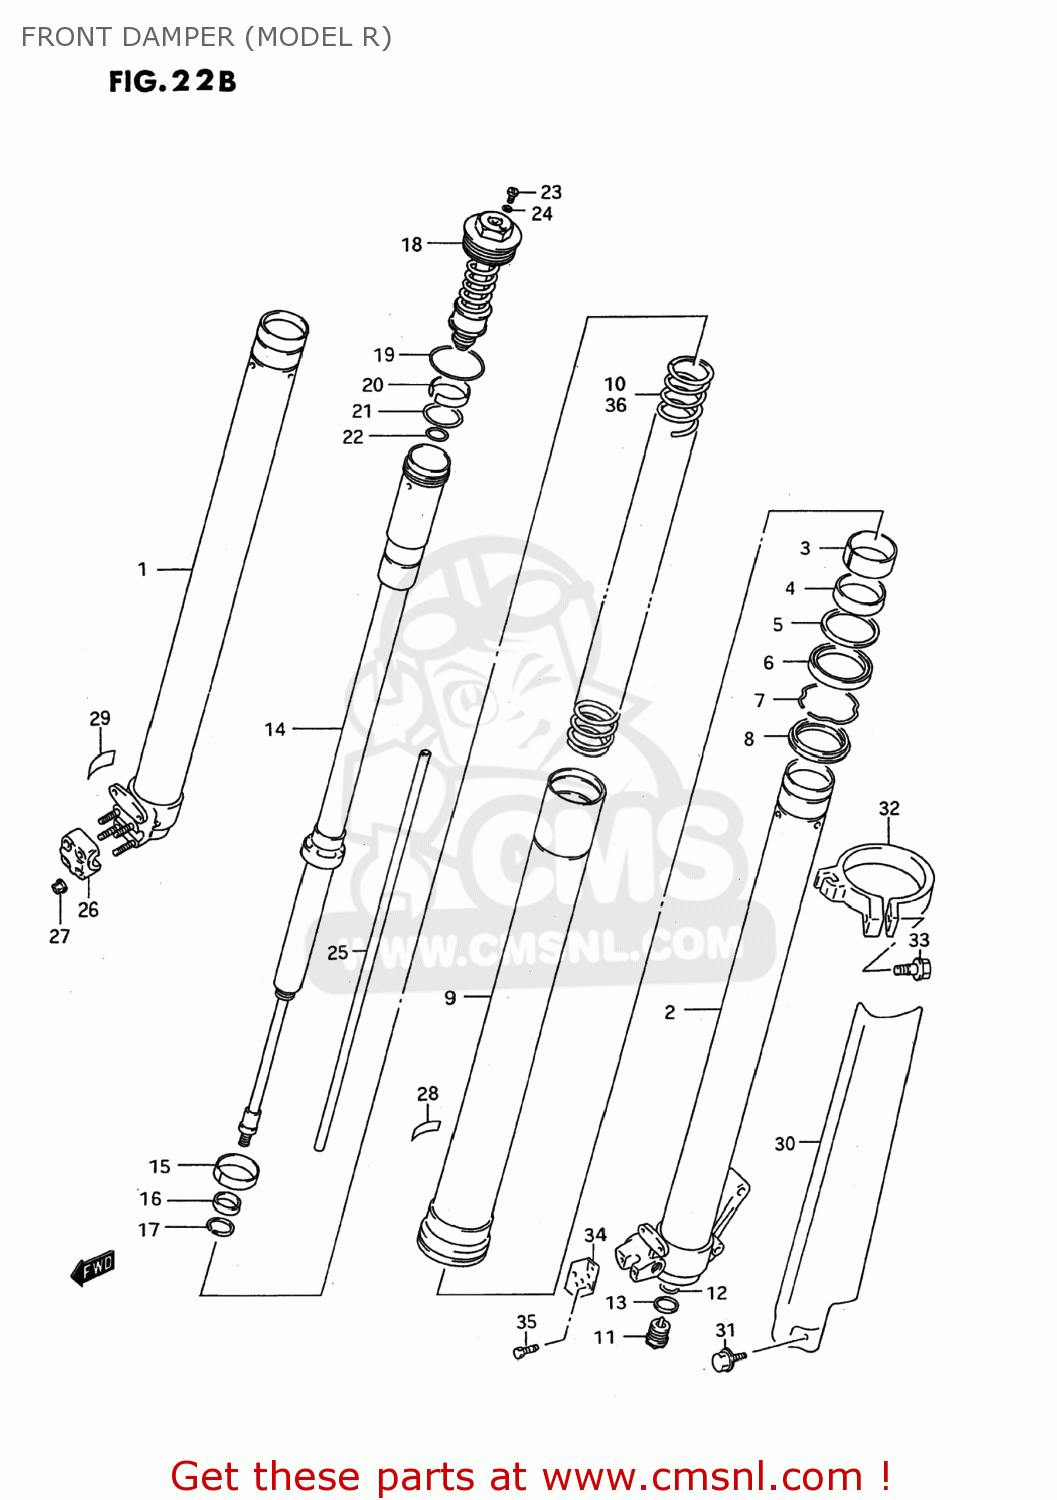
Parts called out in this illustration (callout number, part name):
1	TUBE,INNER,RIGHT
2	TUBE,INNER,LEFT
3	BUSH,SLIDE
4	BUSH,GUIDE
5	SPACER,SEAL
6	SEAL,OIL
7	RING,OIL SEAL STOPPER
8	SEAL,DUST
9	TUBE,OUTER
10	SPRING,MAIN
11	BOLT,CTR
12	GASKET (NAS)
13	O RING,CTR BOLT
14	DAMPER,CARTRIDGE
15	BUSH,DAMPER SLIDE
16	VALVE,OIL LOCK
17	RING,VALVE STOPPER
18	BOLT,FORK
19	O RING
20	BUSH,FORK BOLT SLIDE
21	O-RING,FORK BOLT,CENTER
22	O-RING,FORK BOLT,LOWER
23	BOLT,PLUG
24	O RING,PLUG
25	ROD,PUSH
26	HOLDER,AXLE,R
27	NUT
28	LABEL
29	LABEL
30	PROTECTOR ,RH.
31	BOLT
32	GUIDE,FORK PROTECTOR
33	BOLT,PROTECTOR GUIDE,6
34	GUIDE,HOSE,L
35	BOLT
36	SPRING,MAIN
